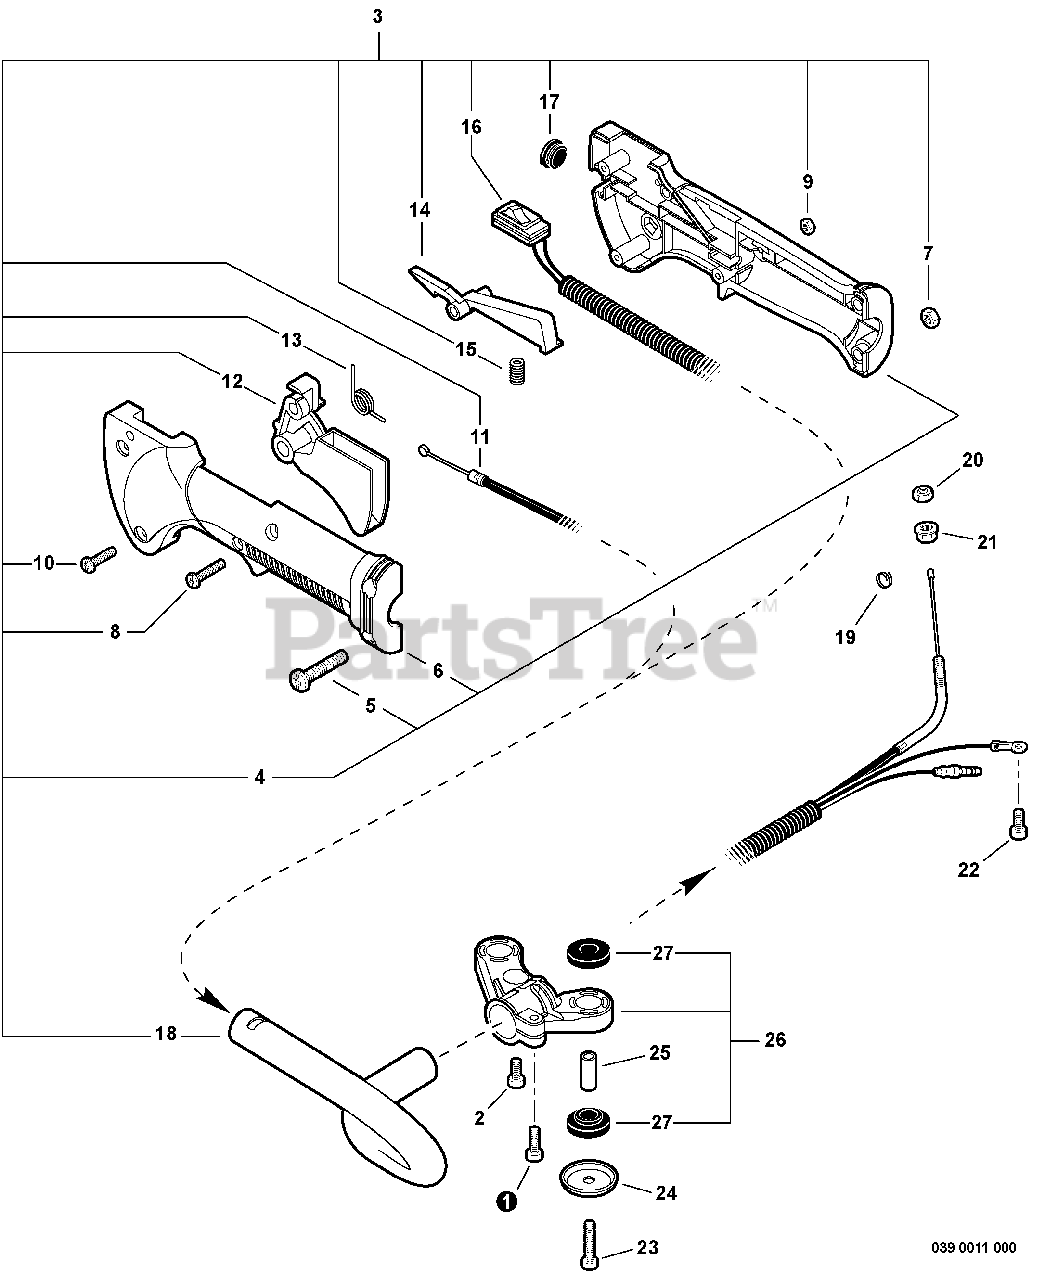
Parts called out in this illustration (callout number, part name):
1	SCREW - 5X16
2	SCREW - 5X12
3	CONTROL HANDLE ASSY
4	CONTROL HANDLE KIT
5	SCREW - 5X20
6	HANDLE, CONTROL - LEFT
7	LOCKNUT
8	SCREW - 4X23
9	NUT - 4
10	SCREW - 4X16 -- TAPPING
11	CABLE, THROTTLE
12	TRIGGER, THROTTLE
13	SPRING, TRIGGER
14	LEVER, TRIGGER LOCKOUT
16	IGNITION SWITCH ASSY
18	HANDLE - REAR
21	NUT - 6 -- FLANGE
22	SCREW - 4X8
23	SCREW - 6
24	WASHER - CUP
25	COLLAR - 6
26	HANDLE BRACKET ASSY
27	CUSHION
